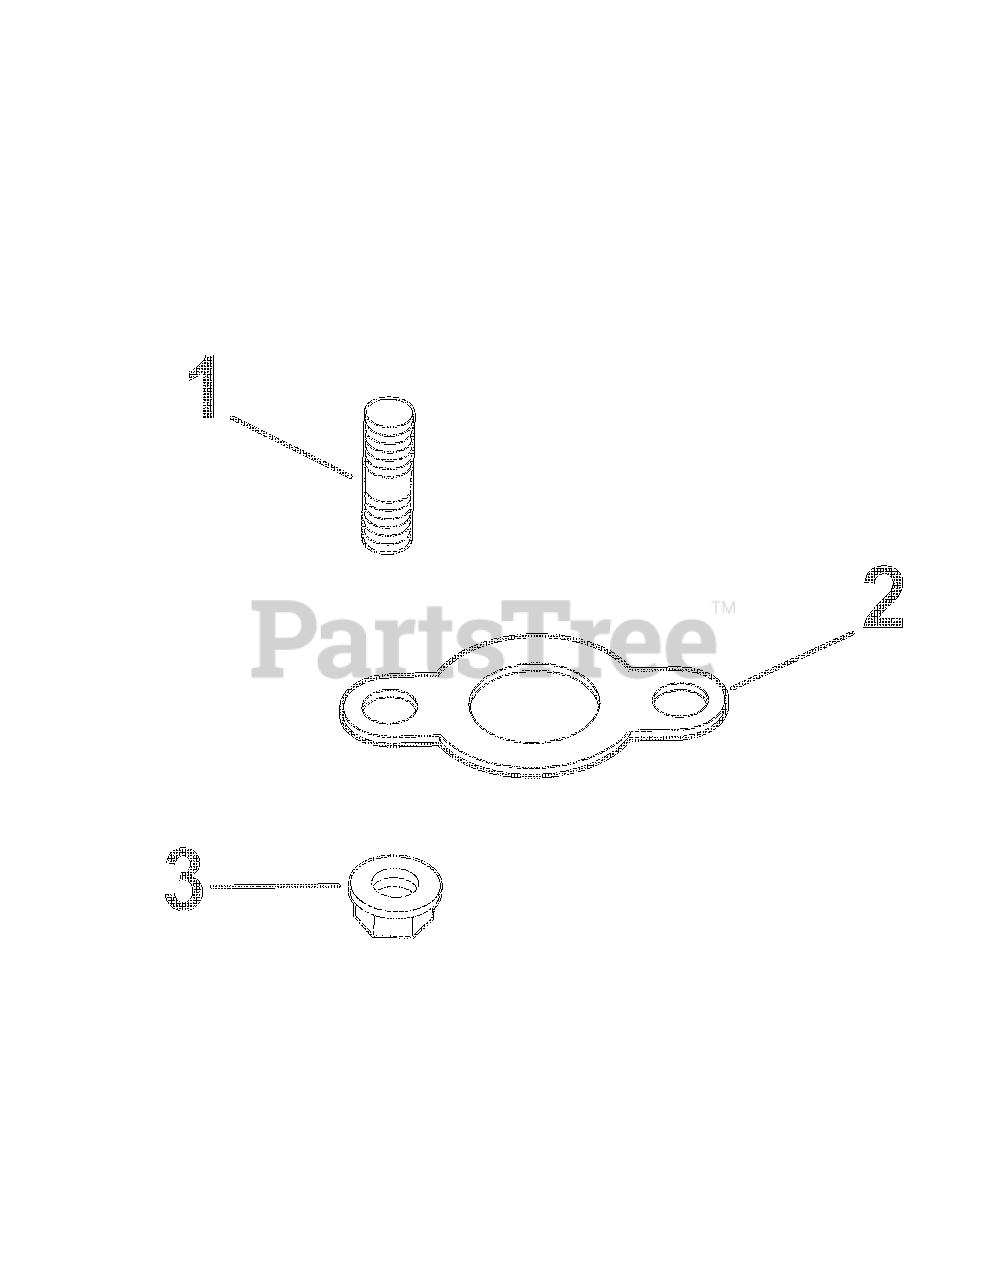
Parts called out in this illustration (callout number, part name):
1	Stud M8x1.25x33 (4)
2	Gasket, exhaust manifold (2)
3	Nut, hex. flange M8x1.25 (5)
